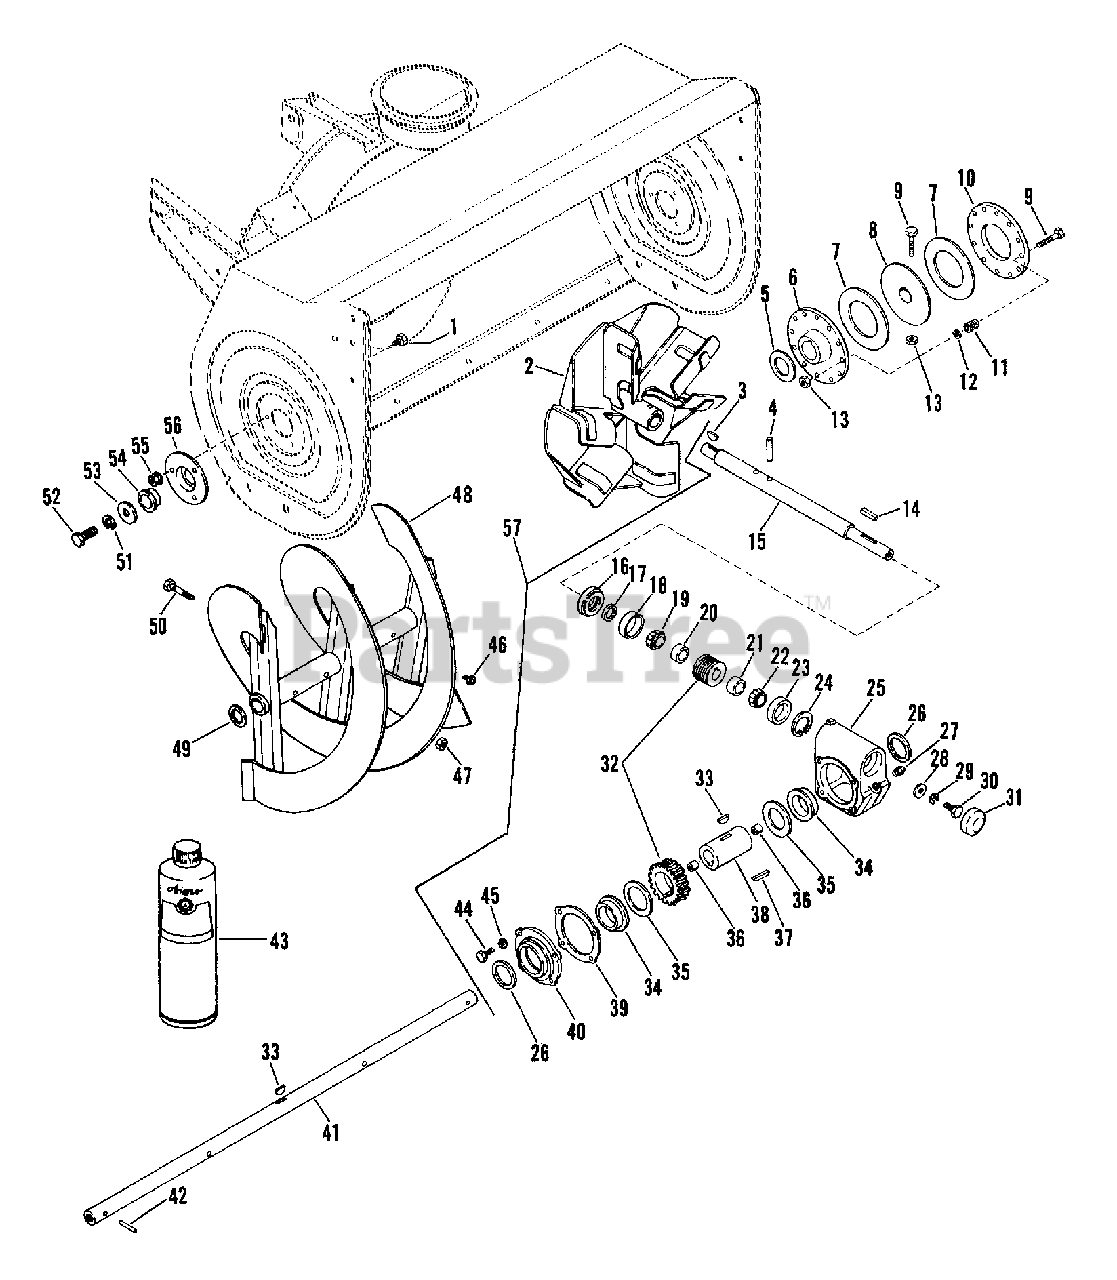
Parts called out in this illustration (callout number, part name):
1	BLT-SERNK SL .25-20X.50 PL
2	FAN - 14"
2	FAN
3	KEY-WDRF .188X.875X.375 SAE11
4	PIN-ROLL .313X1.75
5	WSHR-FL-NYL 1.625X2.500X.060
7	FRICTION DISC
8	DRIVEN PLATE
9	BLT-HEX .31-18X2.00 PL GR5
10	PRESSURE PLATE
11	SG-COMP .156X.665X.75
12	WSHR-FL-STL .323X.625X.062 PL
13	NUT-LK-TOP .312-18 GR C PL
14	KEY-SQ .188X1.0X.188 SAE 8630
15	WORM SHAFT
16	ADJUSTMENT PLUG - 1" SHAFT
16	ADJUSTMENT PLUG
17	SEAL 1.000X1.312X.150
17	SEAL 1.125X1.375X.125
18	BRG-CUP 1.781X.475
18	BRG-CUP1.980X.420
19	BRG-CONE .750X.61
19	BRG-CONE 1.0X.58
20	BSHG, SPCR .755X1.12X.50 PM
20	BEARING SPACER 1.032X1.25X1.78
21	BSHG, SPCR .755X1.12X.50 PM
22	BRG-CONE .750X.61
23	BRG-CUP 1.781X.475
24	RG-RTNG-INT 1.781X.062
25	GEAR CASE - CAST IRON
26	SEAL 1.625X2.125X.250
27	PIPE PLUG
28	WSHR-FL-STL .328X1.0X.094
29	WSHR-LK .312X.097 PL HVY
30	BLT-HEX .31-18X.75 PL GR2
31	DUST CAP
32	WORM & GEAR SERVICE ASSEMBLY
33	KEY-WDRF .25X.875X.375 SAE A
33	KEY-FTHR .25X.875X.25 SAE 8630
34	BSHG-FLG .683X1.87X1.68X2.250
35	WSHR-FL-STL 1.625X2.500X.012
36	BSHG-SLV 1.125X1.250X1.000
37	KEY-SQ .25X.625X.375
38	GEAR CASE SHAFT
40	GEAR CASE COVER
41	SHAFT, 36" RAKE - 1.00 DIA.
41	40 INCH RAKE SHAFT
42	PIN-ROLL .188X1.50
43	ARIENS 16 OZ.BOTTLE OF L2 LUBE
44	BLT-HEX .25-20X.75 PL GR2
45	WSHR-LK-EXT. 250 ID
46	SPIN DRIVE ZERK FITTING
47	NUT-LK .312-18 GR A PL
48	RAKE, LEFT-36"(1"ID X 15.75OD)
48	RAKE, LEFT-40"(1.12ID X 15.75)
48	RAKE, RIGHT-36"(1ID X 15.75OD)
48	RAKE, RIGHT-40(1.12ID X 15.75)
49	WSHR-FL-STL 1.010X1.505X.062PL
50	SHEAR BOLT SERVICE ASSEMBLY
50	BLT-HEX .31-18X2.00 PL GR5
51	WSHR-LK .500X.151 HVY PL
52	BLT-HEX .50-13X1.00 PL GR2
53	WSHR-FL-STL .511X1.441X.125 PL
54	BSHG-FLG 1.000X1.12X.62X1.50BR
55	NUT-LK-FLG .250-20 PL
56	BEARING SUPPORT
57	GEAR CASE - 40" - CAST IRON
57	GEAR CASE - CAST IRON
